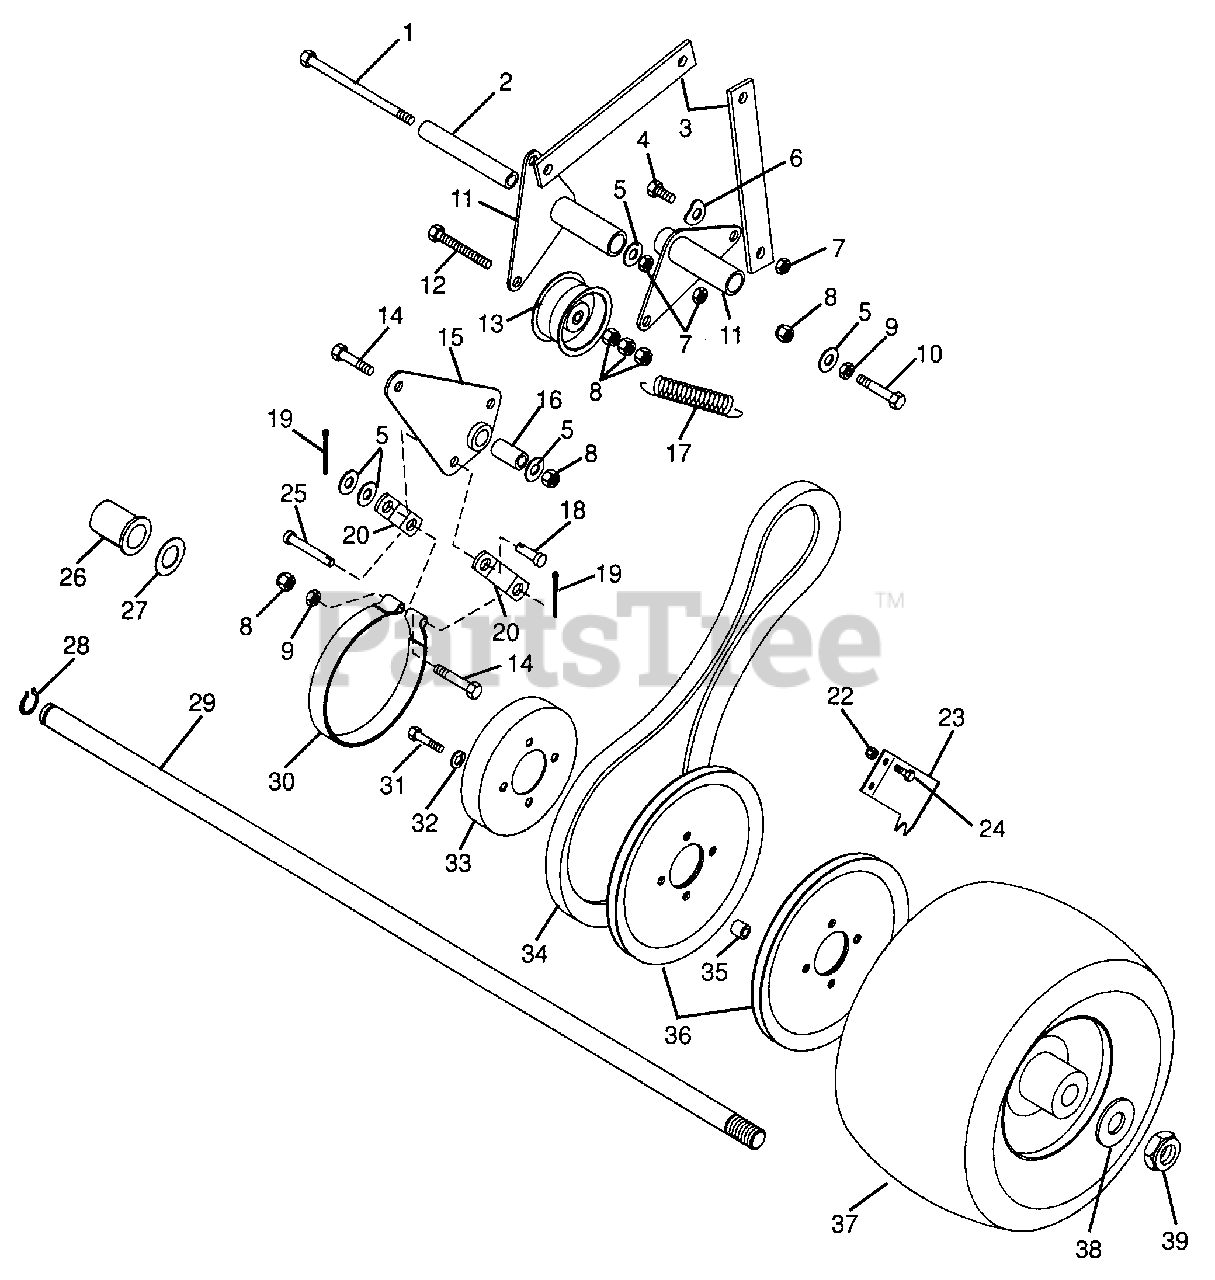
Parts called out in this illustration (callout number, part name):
1	Bolt-Hex .38-16 x 5.00
2	Bush, Steel .385 x .610 x 3.85
3	Strap, Wheel Clutch
4	Bolt-Hex .38-16 x .75 Grade 5
5	Washer-Flat-Steel .406 x .812 x .065
6	Washer-Spring .375
7	Nut-Locking-Center .625-10 Grade 2
8	Nut-Locking-Nylon .375-16 Grade 2
9	Nut-Hex .375-16 Grade 2
10	Bolt-Hex .38-16 x 2.25 Grade 5
11	Weldment, Wheel Clutch Arm
12	Bolt-Hex .38-16 x 3.0 Grade 5
13	Sheave 3.25 x 1.25
14	Bolt-Hex .38-16 x 2.00 Grade 5
15	Weldment, Brake Arm
16	Bushing, Sleeve .391 x .622 x .950
17	Spring-Tension .069 x .62 x 3.50
18	Pin-Clevis .38 x .75
19	Pin-Cotter .12 x .75
20	Link, Brake Arm
21	Nut, Locking 3/4 -10
22	Nut-Locking-Nylon .312-18 Grade 2
23	Cleaner, Pulley Groove Left Hand
23	Cleaner, Pulley Groove Right Hand
24	Bolt-Hex .31-18 x .625
25	Pin-Clevis .372 x 1.25
26	Bushing-Flange 1.010 x 1.38 x 1.4 x 1.65
27	Washer-Thrust 1.55 x 1.002 x .093
28	Ring-Retaining-External .906 x .078
29	Shaft, Axle
30	Assembly, Brake Band, Pro
31	Bolt-Hex .31-18 x 1.50 Grade 5
32	Washer-Lock External .375 x .050
33	Drum, Brake
34	V-Belt, Wheel Drive Set (2)
35	Bushing, Sleeve .385 x .625 x .475
36	Pulley-V 9.00 x 3.75
37	Tire/Wheel Assembly 13 x 6.50-6
38	Washer-Flat-Steel .813 x 1.370 x .100
